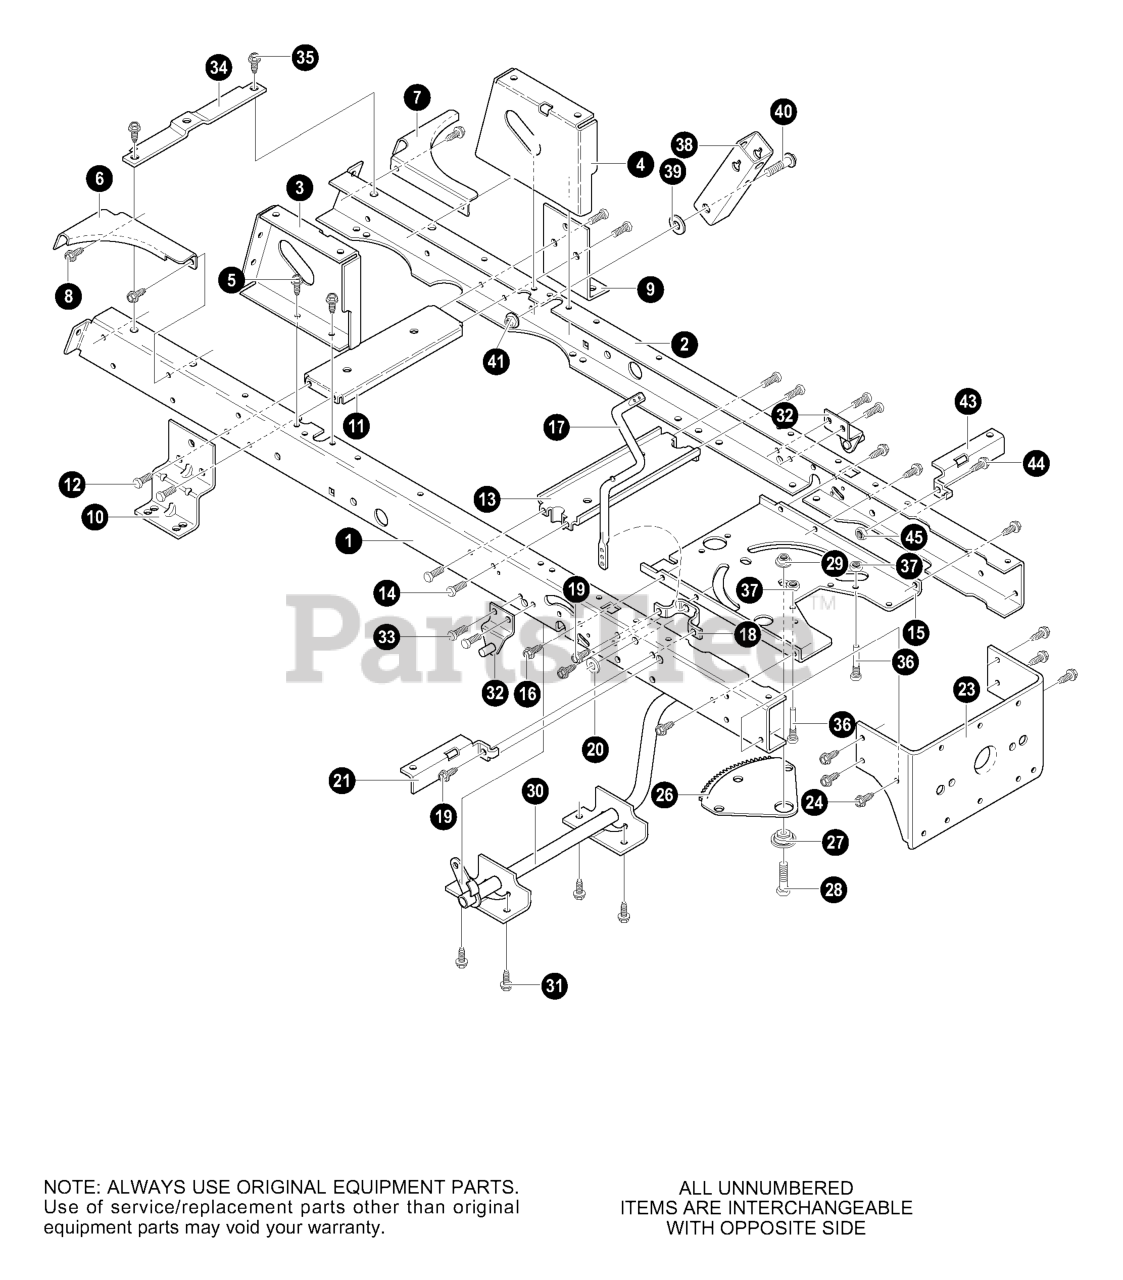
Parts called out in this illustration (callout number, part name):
1	FRAME, RAIL RH
2	FRAME, RAIL LH
3	SUPPORT, SEAT RH
4	SUPPORT, SEAT LH
5	SCREW 5/16-18X.75 HHWATAP
6	BRACE, BACKPLATE RH
7	BRACE, BACKPLATE LH
8	SCREW 5/16-18X.75 HHWATAP
9	BRACKET, TRANSAXLE
10	BRACKET, T/A RH-VST, LH-MST
11	ASM., IDLER MOUNT, REAR
12	SCREW, 5/16-18 x 0.75 HHWATAP
13	ASM. IDLER MOUNT, FRONT
14	SCREW, 5/16-18 x 0.75 HHWATAP
15	PLATE, STEERING MOUNTING
16	SCREW, 5/16-18 x 0.75 HHWATAP
17	CRANK, PTO
18	BRACKET, BELL CRANK
19	SCREW, 5/16-18 x 0.75 HHWATAP
20	WASHER, FLAT .469X.92X.065
21	BRACKET, SEAT DECK R.H.
23	BRACKET, HANGER REAR
24	SCREW, 5/16-18 x .75 HHWATAP
26	GEAR, SECTOR
27	BEARING, SECTOR GEAR
28	SCREW, 5/16-18 x 1.00
29	NUT, 5/16-18 HEXKEPS 15X113
30	ASM., CLUTCH/BRAKE PEDAL
31	SCREW, 5/16-18 x 0.75 HHWATAP
32	BRACKET, SUSPENSION ASM.
33	SCREW, 5/16-18 x 0.75 HHWATAP
34	BRACE, RAIL
35	SCREW, 5/16-18 x 0.75 HHWATAP
36	ZINC SCREW GUIDE
37	NUT, 5/16-18 HEXWDFLLK WHIZ
38	BRACKET, PIVOT
39	WASHER, FLAT .390X1.25X.119
40	BOLT, .562X1.563 HHSH 3/8-16
41	NUT, 3/8-16 HWDFLLK MACK 15X84
43	BRACKET, SEAT DECK L.H.
44	SCREW, 5/16-18 x 0.75 HHWATAP
45	NUT, 5/16-18 HEXWDFLLK WHIZ
